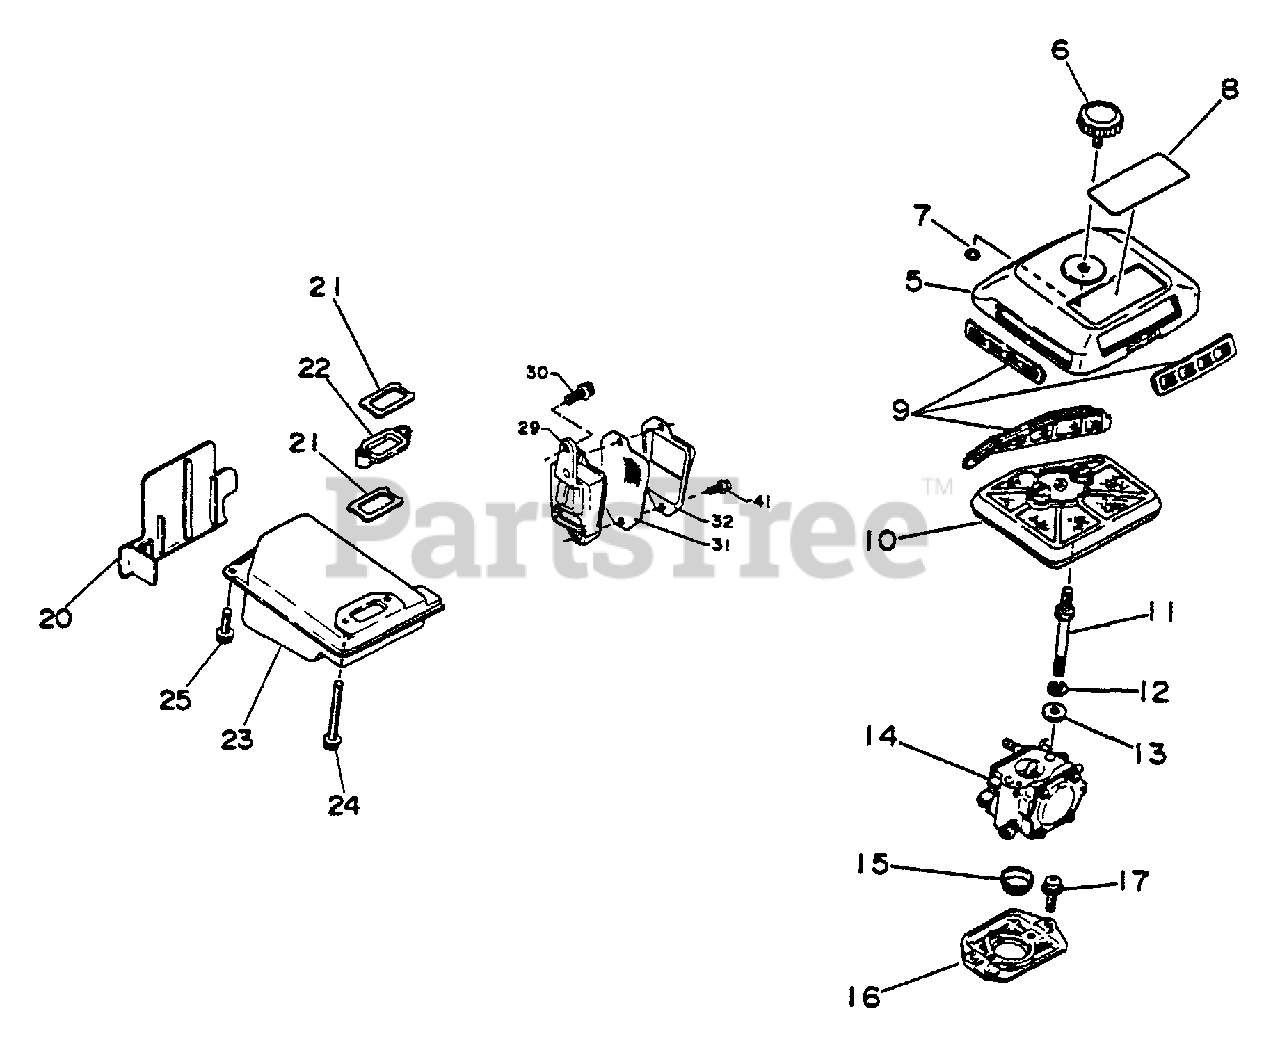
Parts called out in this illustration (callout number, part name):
5	COVER, AIR FILTER
6	THUMBSCREW
7	O-RING - 3
8	LABEL
9	DEBRIS FILTER KIT
10	FILTER, AIR
11	STUD
12	LOCKWASHER - 5
13	WASHER - 5
14	CARBURETOR HAD-20B
15	SEAL
16	ADAPTOR
17	SCREW - 4X12
20	INSULATOR
21	GASKET, EXHAUST
22	BAFFLE, MUFFLER
23	MUFFLER
24	SCREW - 5X40
25	SCREW - 5X20
30	SCREW - 5X14
31	SCREEN, SPARK ARRESTOR
32	GUIDE, EXHAUST
41	SCREW - 4X10
